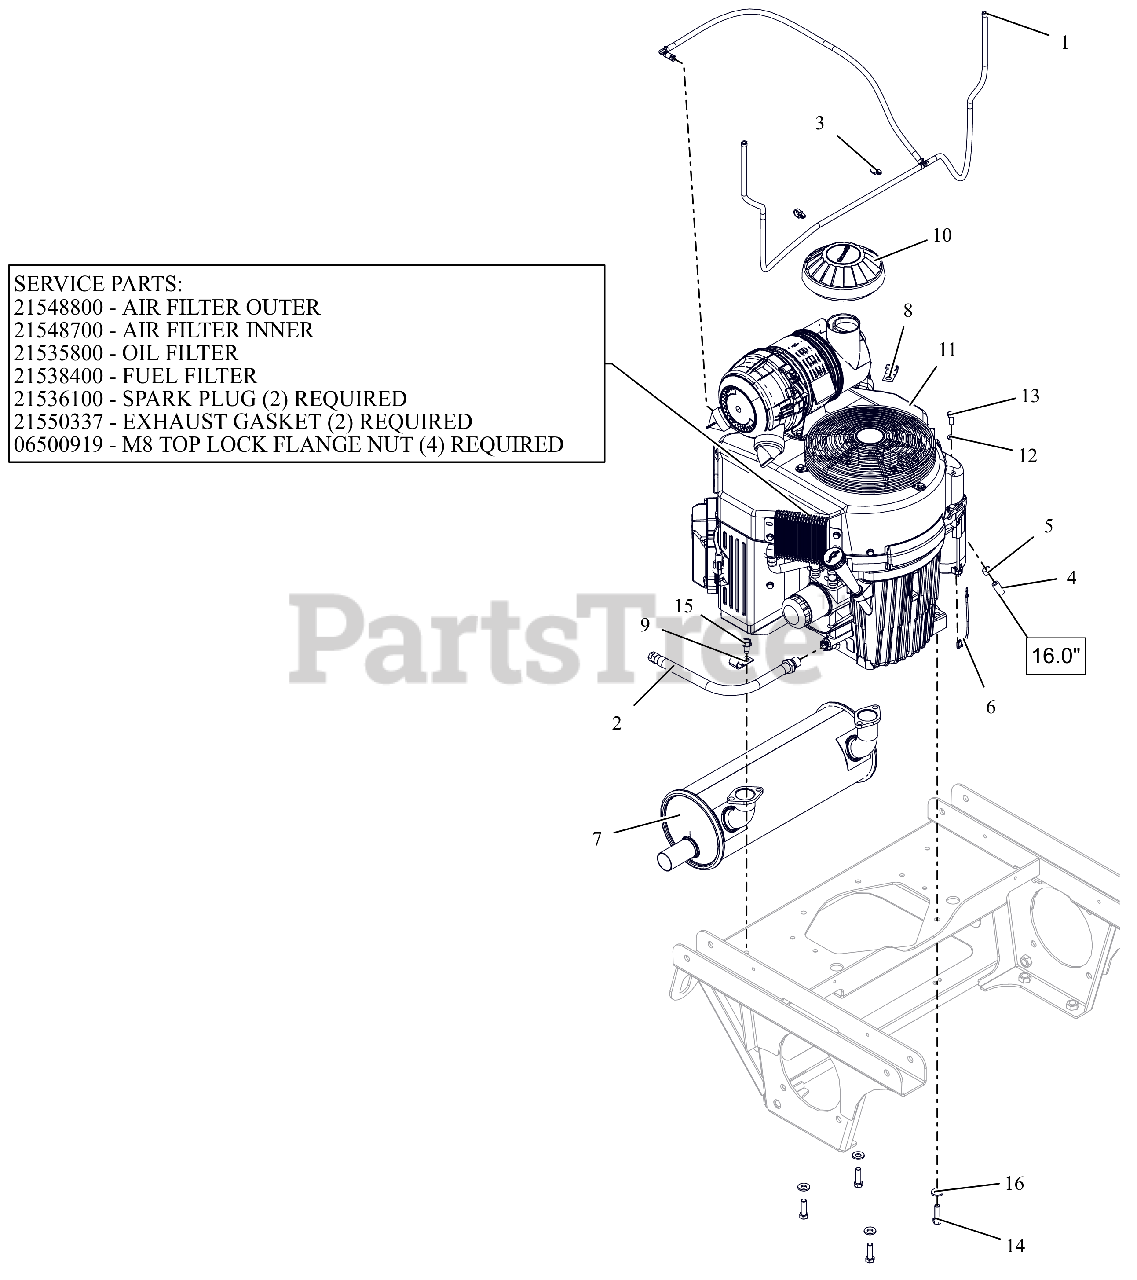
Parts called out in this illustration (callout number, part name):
1	ASM, VAPOR LINE
2	HOSE, OIL DRAIN
3	ROUTING CLIP (1/2" ID)
4	HOSE, .25 LOW-PERM BULK GAS
5	CLAMP, FUEL LINE
6	LEAD - STARTER SOLENOID
7	MUFFLER - 34HP KAWASAKI VERT.
10	CAP, AIR CLEANER INTAKE (2")
11	ENGINE-KAWASAKI FX921
11	FILTER, OUTER
11	FILTER, INNER - KAW
11	FILTER,OIL - KAW
11	FUEL FILTER - KAWASAKI
11	PLUG, SPARK
11	GASKET, EXHAUST (11061-7061)
11	NUT-LK-TOP-FLG M8 ZCC
12	WSHR,LK-REG .312X.078 ZCC
13	BLT, HEX M8-1.25X20 G8.8 ZCC
14	BLT, HEX .38-16X1.25 G5 ZCC NT
15	SCR,TAP .375-16X.75 HWH TR ZCC
16	WASHER, 3/8" SPRING DISC
